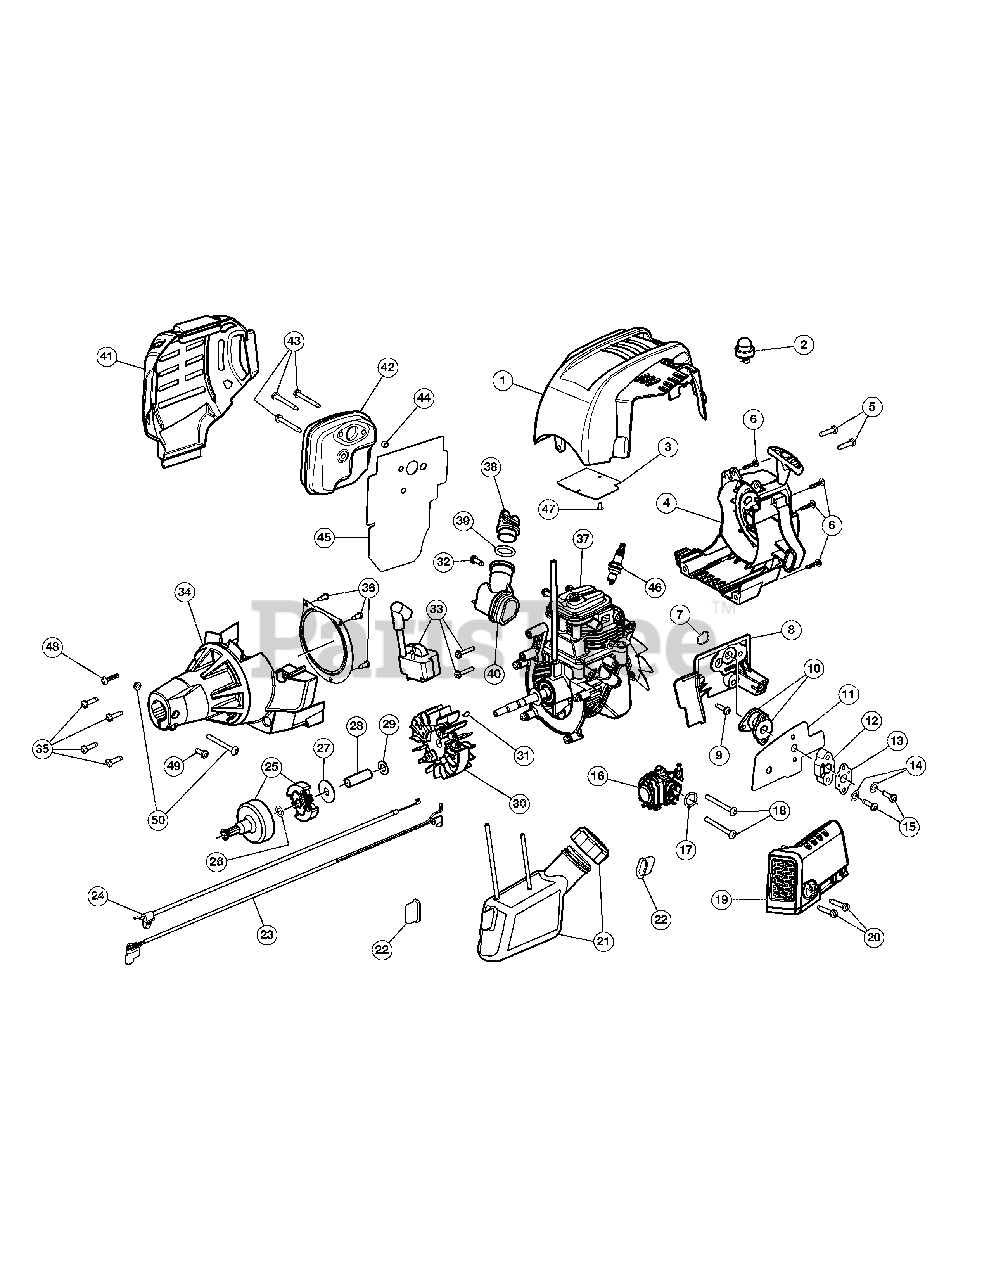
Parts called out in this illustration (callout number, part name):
1	Top Housing Assembly (Incl. 3 & 47)
2	Air Purge Primer
3	Top Cover Gasket
4	Starter Housing Assembly (Incl. 5 & 6)
8	Intake Port
9	Screw
10	Boot Assembly
11	Carburetor Gasket
12	Insulator
13	Insulator Gasket
15	Screw
16	Carburetor Assembly (Incl. 17)
19	Air Cleaner Assembly (Incl. 20)
21	Fuel Tank Assembly
22	Fuel Tank Pad
23	Lead Wire
24	Throttle Cable
25	Clutch Assembly (Incl. 26 & 27)
26	Thrust Washer
27	Clutch Washer
28	Power Shaft Spacer
29	Washer
30	Flywheel Assembly (Incl. 31)
32	Screw
33	Module Assembly
34	Clutch Cover Assembly (Incl. 36)
37	Short Block Assembly
38	Oil Fill Plug
40	Oil Fill Tube Assembly (Incl. 38 & 39)
41	Muffler Housing
42	Muffler Assembly (Incl. 43 - 46)
43	Screw
44	Air Cleaner Spacer
45	Muffler Gasket
46	Spark Plug
49	Anti-rotation Screw
50	Clamp Hardware
